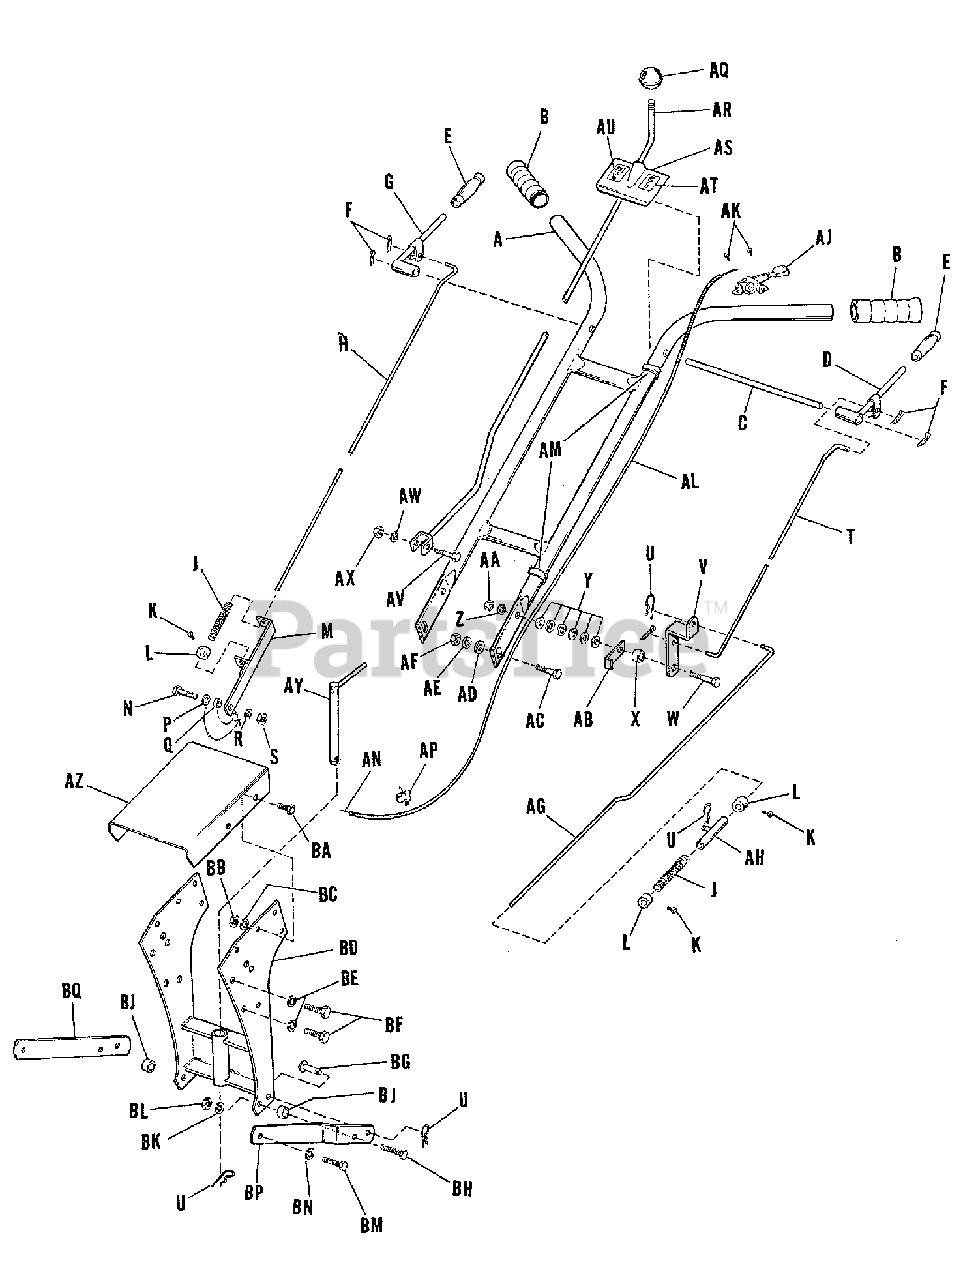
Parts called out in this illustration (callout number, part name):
A	HANDLE ASSEMBLY
B	GRIP, Handle
C	PIN, Lever
D	LEVER ASSEMBLY, L.H.
F	PIN, Cotter, 3/32" Diameter x 3/4" LG
G	LEVER ASSEMBLY, R.H.
H	ROD, Engine Clutch
J	SPRING, Clutch Rod
K	SCREW, Set, Square Head, Cup Point, 1/4"-20 NC x 3/8" LG
L	COLLAR, Set
M	GUIDE ASSEMBLY, Clutch Rod
N	CAPSCREW, Hex Head, 3/8"-16 NC x 1" LG
P	WASHER, Plain, 3/8"
R	WASHER, Lock, 3/8"
S	NUT, Hex, Full, 3/8"-16 NC
T	ROD, Upper Idler
U	SPRING, Clip
V	LEVER, Lower Clutch
W	CAPSCREW, Hex Head, 3/8"-16 NC x 1-3/4" LG
Y	WASHER, Plain, 3/8"
Z	WASHER, Lock, 3/8"
AA	NUT, Hex, Full, 3/8"-16 NC
AB	LEVER, Stop
AC	CAPSCREW, Hex Head, 3/8"-16 NC x 1-1/4" LG
AD	WASHER, Plain, 3/8"
AE	WASHER, Lock, 3/8"
AF	NUT, Hex, Full, 3/8"-16 NC
AG	ROD, Lower Clutch
AH	SOCKET ASSEMBLY, Rod
AJ	CONTROL, Throttle Lever
AK	SCREW, Round Head, Self Tapping, #10-24 x 1/2" LG
AL	THROTTLE CABLE
AM	CLIP, Cable
AN	WIRE, Throttle
AP	CLIP, Cable, Speed
AQ	BALL, Shift Lever
AR	ROD ASSEMBLY, Shift
AS	GUIDE ASSEMBLY, Rod
AT	DECAL, Shift, L.H.
AU	DECAL, Shift, R.H.
AV	CAPSCREW, Hex Head, 5/16"-18 NC x 1-1/2" LG
AW	WASHER, Lock, 5/16"
AX	NUT, Hex, Full, 5/16"-18 NC
AY	PIN ASSEMBLY, Hitch
AZ	COVER, Frame
BA	CAPSCREW, Hex Head, 5/16"-18 NC x 5/8" LG
BB	NUT, Hex, Full, 5/16"-18 NC
BC	WASHER, Lock, 5/16"
BD	FRAME ASSEMBLY, Rear
BE	WASHER, Lock, 7/16"
BF	CAPSCREW, Hex, Head, 7/16"-14 NC x 1" LG
BG	PIN, Round Head
BH	CAPSCREW, Hex Head, 3/8"-16 NC x 1-1/4" LG
BK	WASHER, Lock, 3/8"
BL	NUT, Full, Hex, 3/8"-16 NC
BM	CASPCREW, Hex Head, 7/16"-14 NC x 1" LG
BN	WASHER, Lock, 7/16"
BP	BAR, Draw, L.H.
BQ	BAR, Draw, R.H.
